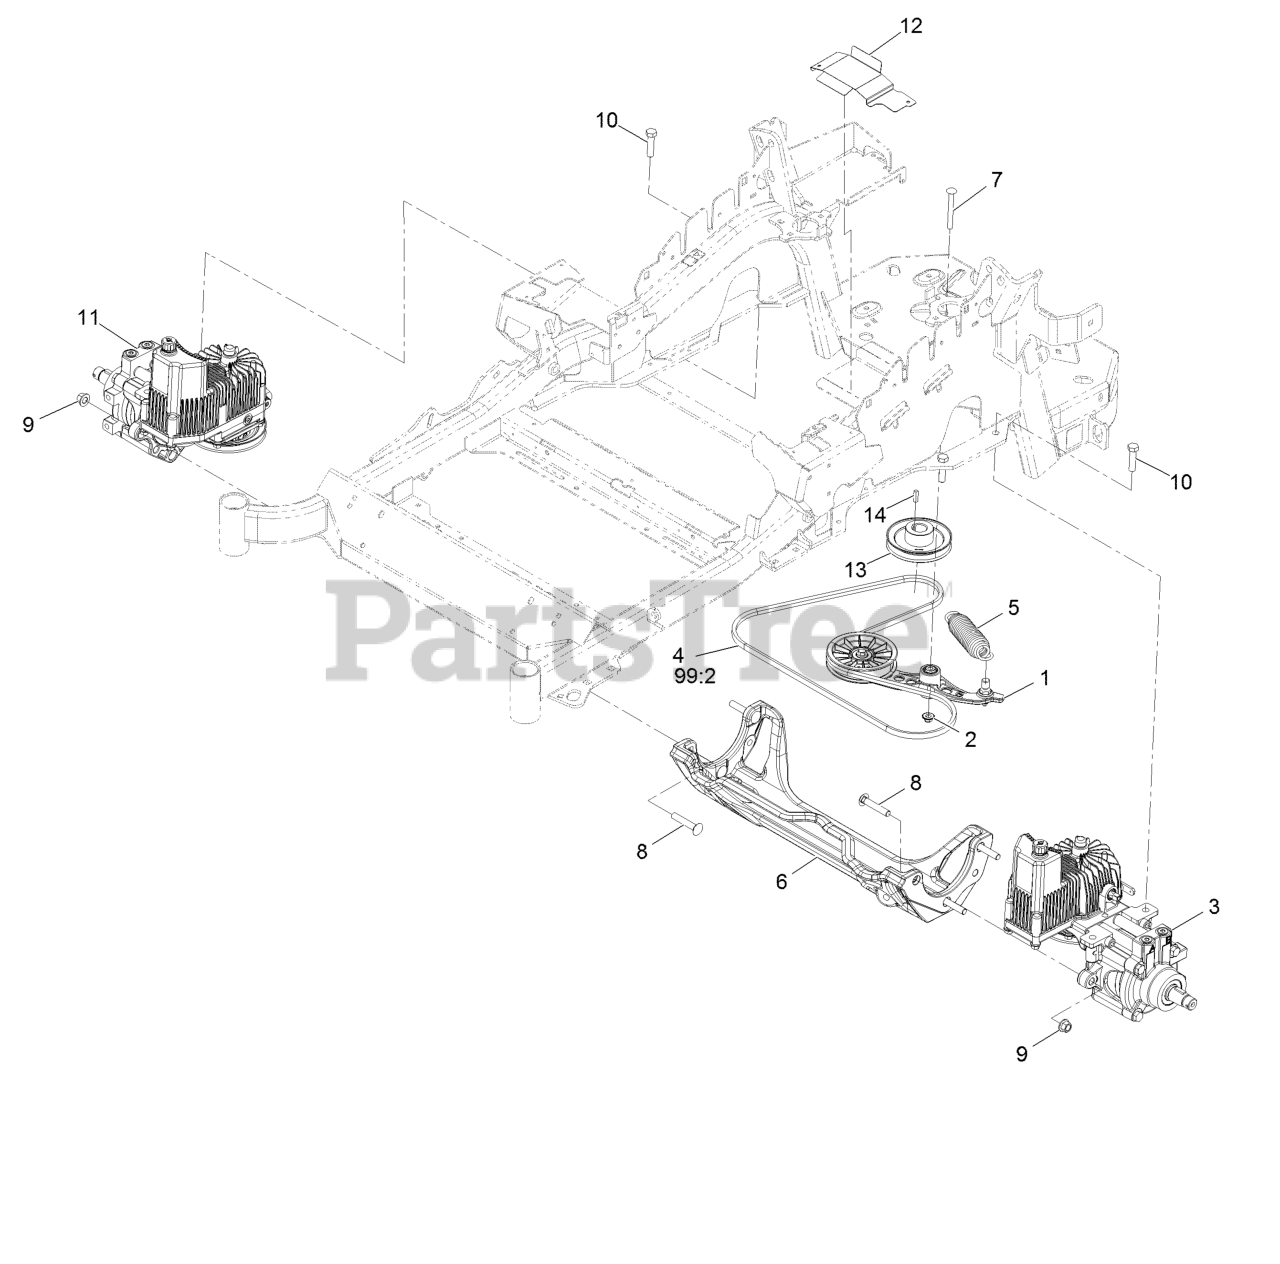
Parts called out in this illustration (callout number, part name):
1	Pump Idler ASM
2	Nut-Nyloc 3/8-16 Flg
3	LH Hydro ASM (12Cc No Fan)
4	Belt-V
5	Spring-Extension
6	Cradle-Hydro
7	Bolt-Carriage Shoulder 3/8-16 X 3 1/2
8	Screw-CARR
9	Nut-Lock 1/2-13
10	Screw-HH 1/2-13 X 1 1/4
11	RH Hydro ASM (12Cc No Fan)
12	Guard-Belt
13	Sheave-Pump, Drive
14	Key-Machine 1/4 X 1/4 X 1
99	Bottle-Oil, 32Oz Hydraulic
99	Filter-Hydro
99	Bottle,Oil 1 Gallon Hydraulic
99	Kit,Hydro Service
99:1	Bottle-Oil, 32Oz Hydraulic
99:2	Belt-V
99:3	Filter-Hydro
